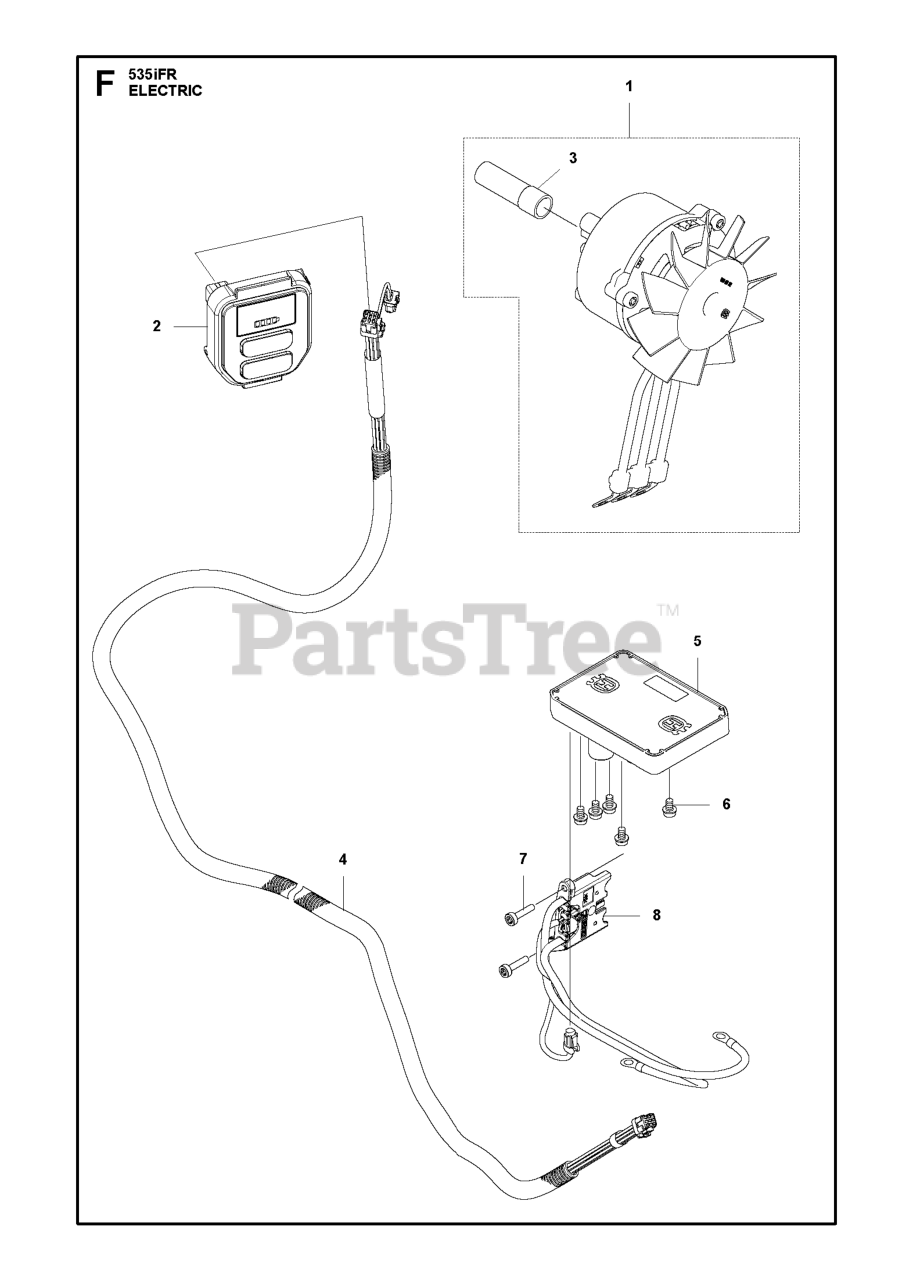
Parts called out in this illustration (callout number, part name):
2	CONTROL PANELS
2	Controls
5	CONTROL UNITS
6	SCREW ITXSCFM M5X8 T27 10.9 Z
7	SCREW ITXSCT PW4.2X18 10.9 ZN
